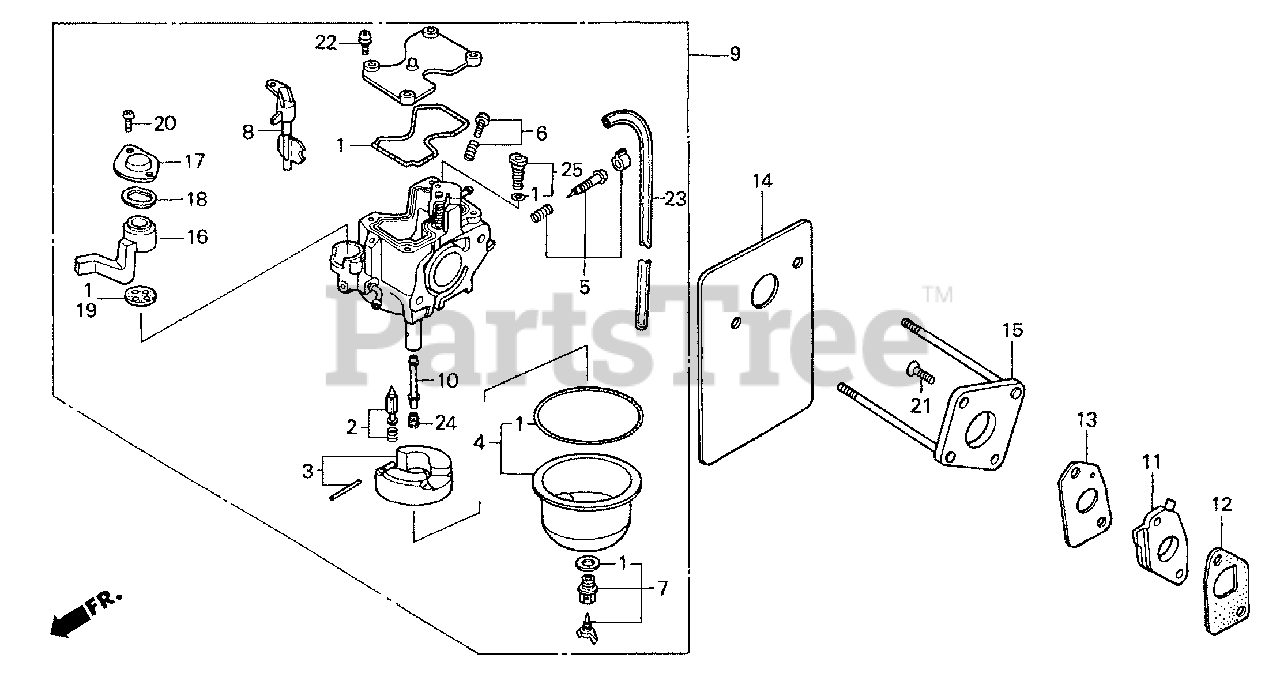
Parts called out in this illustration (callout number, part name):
1	GASKET SET
2	VALVE SET, FLOAT
4	CHAMBER SET, FLOAT
5	SCREW SET, PILOT
6	SCREW SET
7	SCREW SET
8	LEVER SET, CHOKE
9	CARBURETOR ASSY. (BF22B D)
9	CARBURETOR ASSY.
10	NOZZLE, MAIN
11	INSULATOR, CARBURETOR
12	GASKET, INSULATOR
13	GASKET, CARBURETOR
14	GASKET, CARBURETOR
15	PLATE, CARBURETOR JOINT
16	LEVER, VALVE
17	PLATE, LEVER SETTING
18	SPRING, VALVE LEVER
19	GASKET, VALVE
20	SCREW, PAN (3X8)
21	SCREW, FLAT (5X20)
22	SCREW-WASHER (4X12)
23	BULK HOSE, VINYL (4.5X8X1000) (4.5X8X750)
24	JET, MAIN (#60)
24	JET, MAIN (#62)
24	JET, MAIN (#65)
25	JET SET, PILOT (#35)
